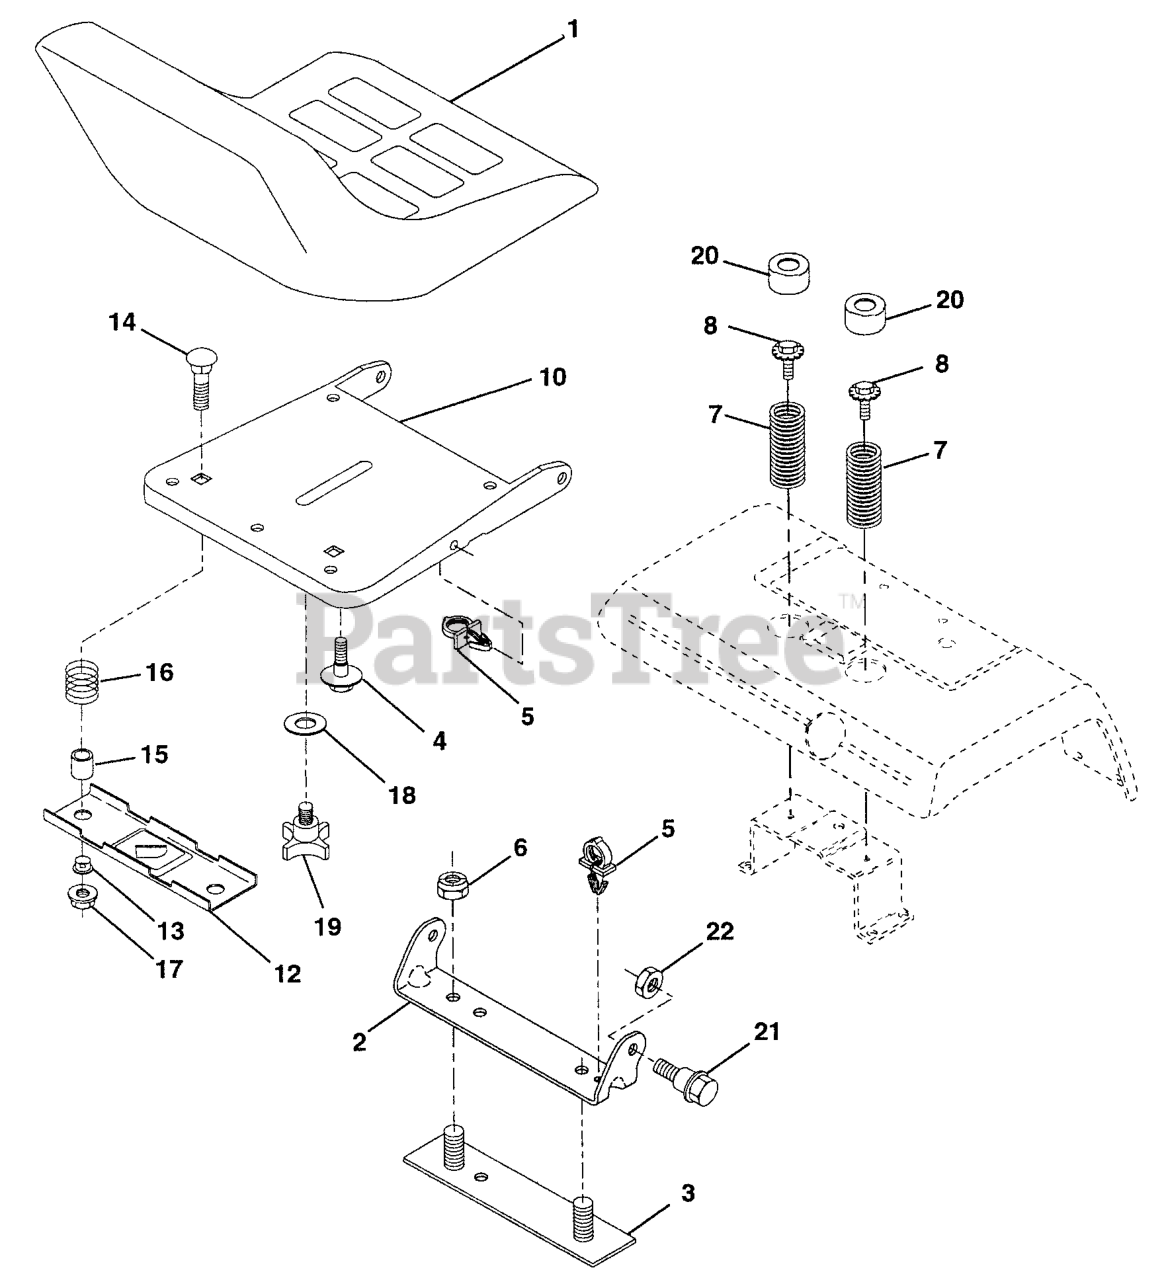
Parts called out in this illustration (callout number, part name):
1	SEAT
2	SEAT PIVOT BRKT
3	STRAP
4	BOLT,SHOULD
6	NUT
7	SPRING COMPRESSION
8	BOLT HEX WASHER HD 5/16-18
10	SEAT PAN
12	BRKT SWITCH
14	Bolt, Carriage 1/4-20 X 1-3/8
15	SPACER SPLIT
16	SPRING COMPRESSED
17	NUT T
19	KNOB 1/2" YT
20	CAP SPRING
21	BOLT.SHOULDER.5/16-18
22	LOCKNUT
